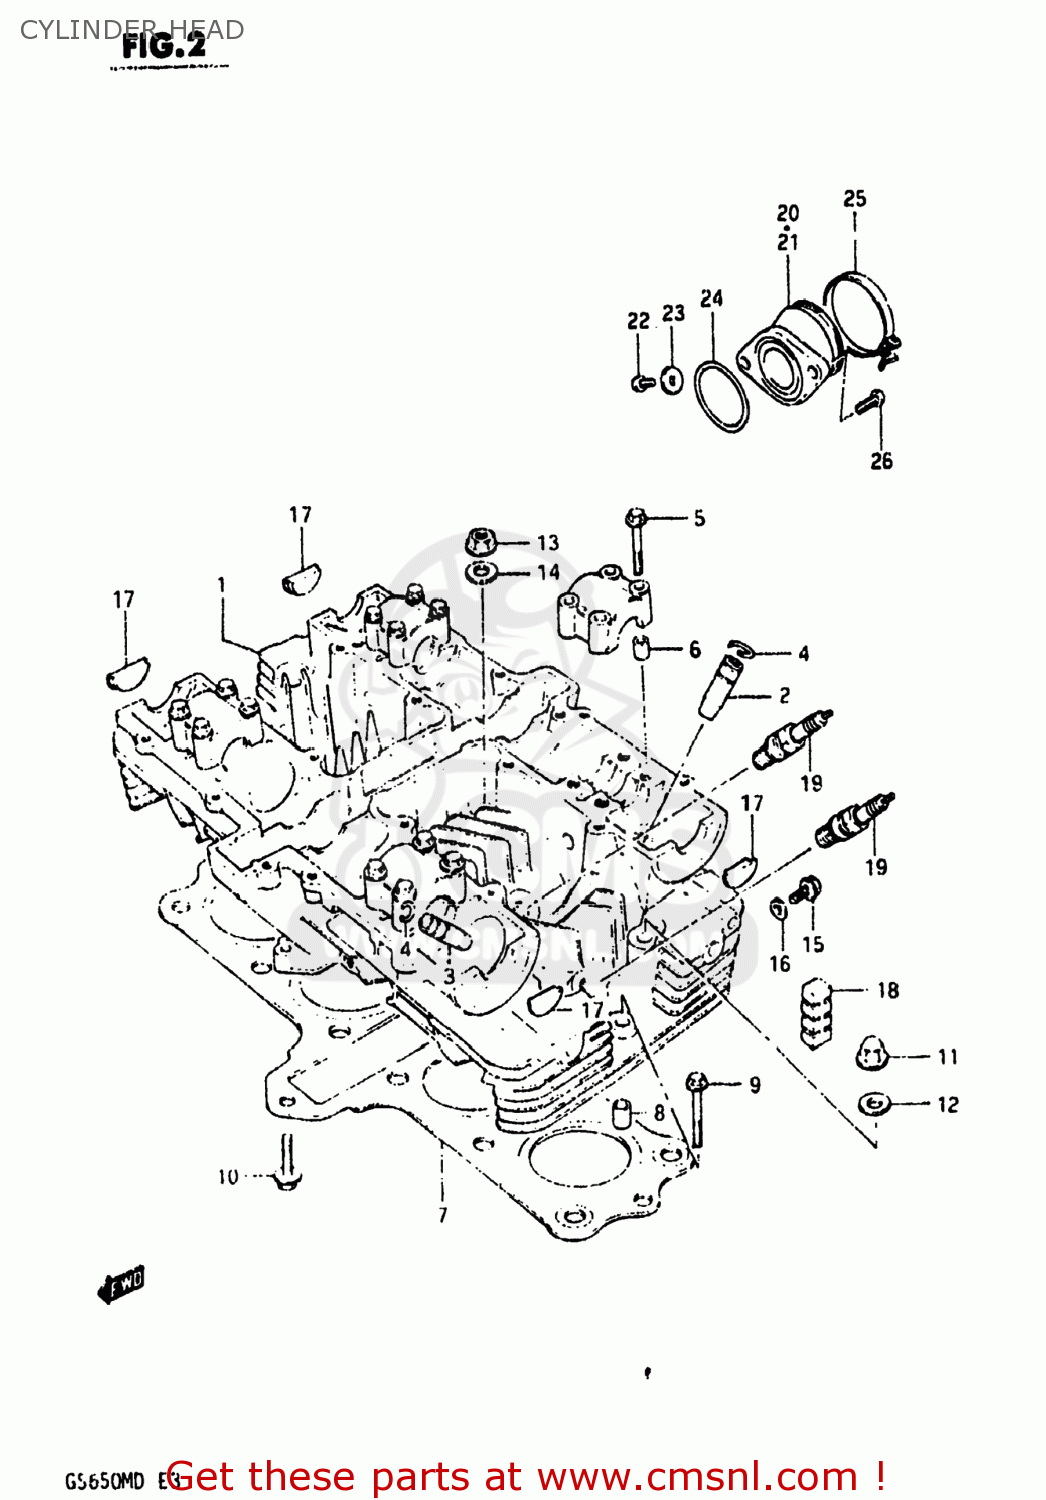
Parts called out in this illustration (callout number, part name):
1	HEAD,CYLINDER
2	GUIDE,INTAKE VALVE
3	GUIDE,EXHAUST VALVE
4	RING,SNAP
5	BOLT(6X39)
6	PIN(6.2X8X11)
7	GASKET,CYLINDER HEAD (NAS)
8	PIN
9	BOLT (6X45)
10	BOLT 6X30
11	NUT
12	GASKET (NAS)
13	NUT
14	WASHER(8.5X19X2.3)
15	BOLT 6X12
16	GASKET (NAS)
17	PLUG
18	PAD,CYLINDER
19	SPARK PLUG D8EA
20	PIPE,INTAKE,R
21	PIPE,INTAKE,L
22	BOLT
23	WASHER,5MM
24	O-RING
25	CLAMP
26	SCREW
